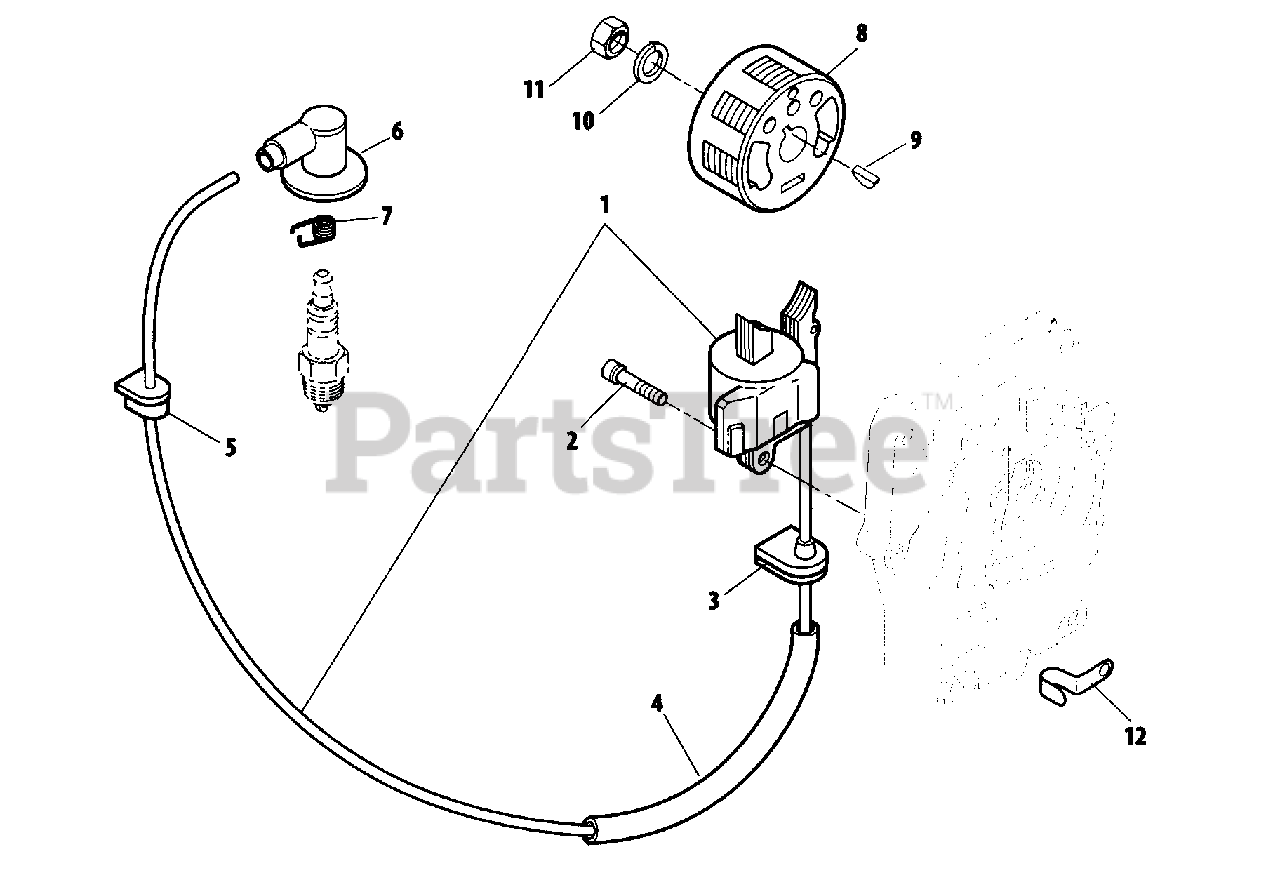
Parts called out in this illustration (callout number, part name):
1	COIL
2	BOLT 5
3	GROMMET
4	TUBE, INSULATOR
5	GROMMET
6	CAP, SPARK PLUG
7	TERMINAL, SPARK PLUG
8	FLYWHEEL
9	KEY, WOODRUFF 3×10
10	WASHER, SPRING 10
11	NUT 10×1.25
12	CLIP
